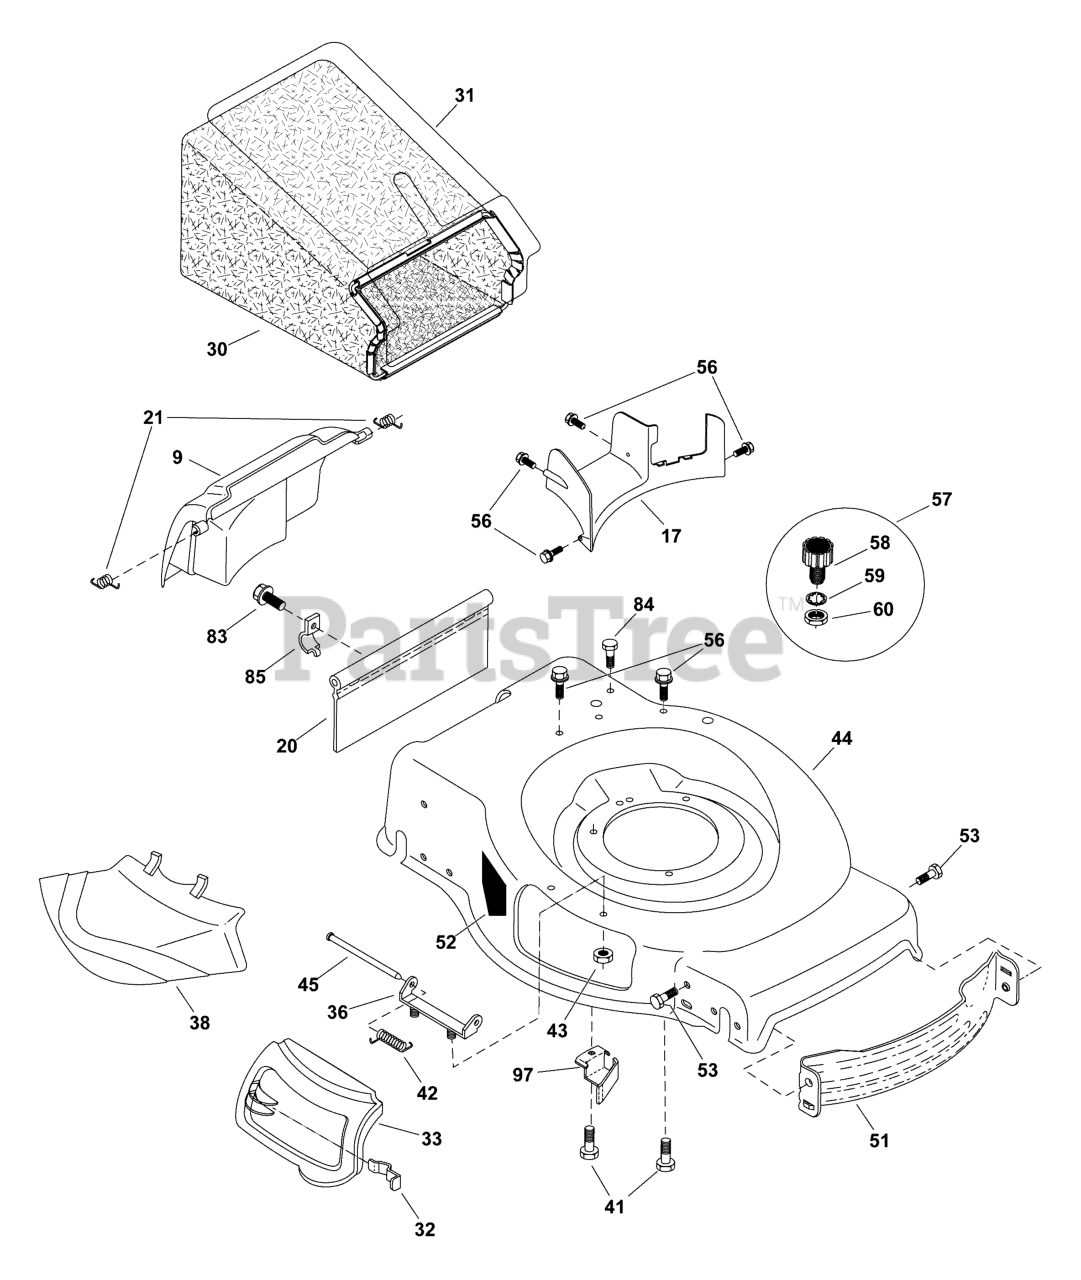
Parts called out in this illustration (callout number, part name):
9	DEFLECTOR
17	BAFFLE, Rear
20	SKIRT, Rear
21	Spring, Rear Door, LH, Black
30	GRASSBAG
31	FRAME, Grass Bag
32	Latch, Mulcher Door
33	DOOR, Mulcher
36	Hinge Bracket Assembly
38	Discharge Deflector
41	SCREW, 3/8 Hex HD Thread Rolled
42	Spring, Torsion
43	Nut, Hex, Flanged 1/4-20
44	HOUSING. Lawn Mower
45	HOSE-FUEL
51	BAFFLE, FRONT
52	Decal Deflect WRN. Cutfinger
53	SCREW, FRONT BAFFLE
56	Screw, Hex Washer Head, #13 x 3/4
57	KIT, Washout Port
58	WASHOUT PORT
59	WASHER, Lock, Internal Tooth
60	NUT, Lock, With O-Ring
83	CAPSCREW
84	FASTENER, Push
85	BRACKET, MOUNTING
97	GUIDE, Belt
